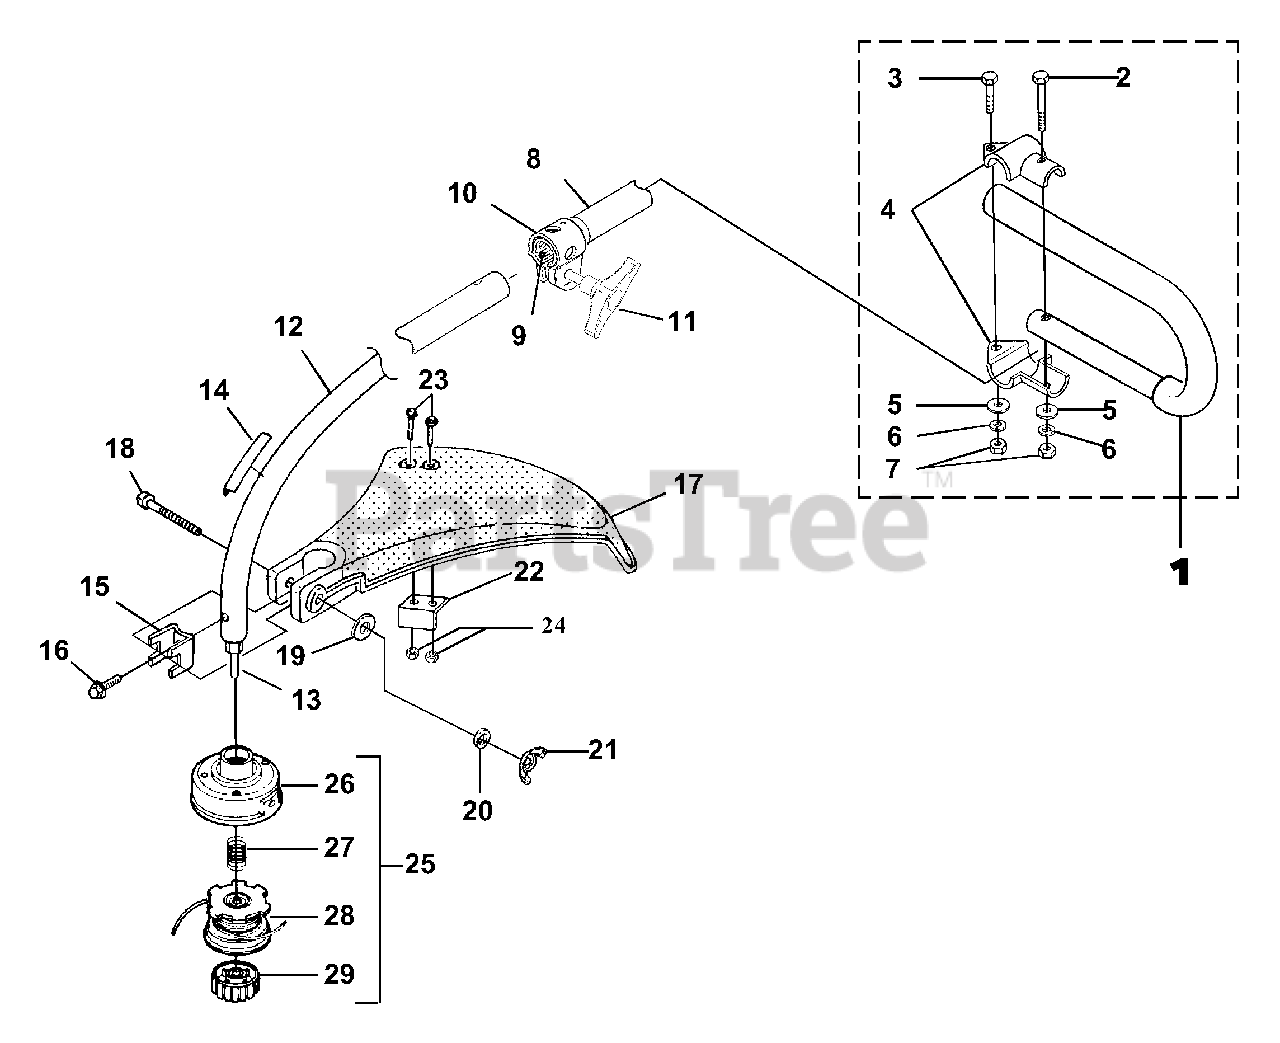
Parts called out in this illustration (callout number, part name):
1	HANDLE("J")
2	SCREW-Hex Hd. (1/4-20 X 1 1/2")
3	SCREW-Hex Hd. (1/4-20 X 1")
4	CLAMP-Handle Bar
5	WASHER-Flat (1/4")
6	WASHER-Lock (1/4")
7	NUT-Hex (1/4-20)
8	DRIVESHAFT ASSY. (Upper)
9	FLEXSHAFT w/Collar & Liner
10	COUPLER KIT
11	KNOB
12	DRIVESHAFT HOUSING (Lower)
13	SHAFT-Flex
14	DECAL-Warning
15	CLAMP
16	SCREW-Sems Hex (10-24 X 3/8")
17	DEFLECTOR & BLADE KIT (55 Deg.)
18	SCREW-Cap Hex Hd. (1/4-20 X 2")
19	WASHER-Flat (1/4")
20	WASHER-Lock (1/4")
21	NUT-Wing, Washer Faced (1/4-20)
22	BLADE-Cut-Off
23	SCREW-Mech. Hex Hd. (10-24 X 7/8")
24	NUT-Hex (10-24)
25	STRINGHEAD-Complete (.095")
26	HOUSING & EYELET (Dual Line)
27	SPRING-Compression
28	SPOOL & STRING (.095")
29	RETAINER-Spool (R.H. Thread, Black)
